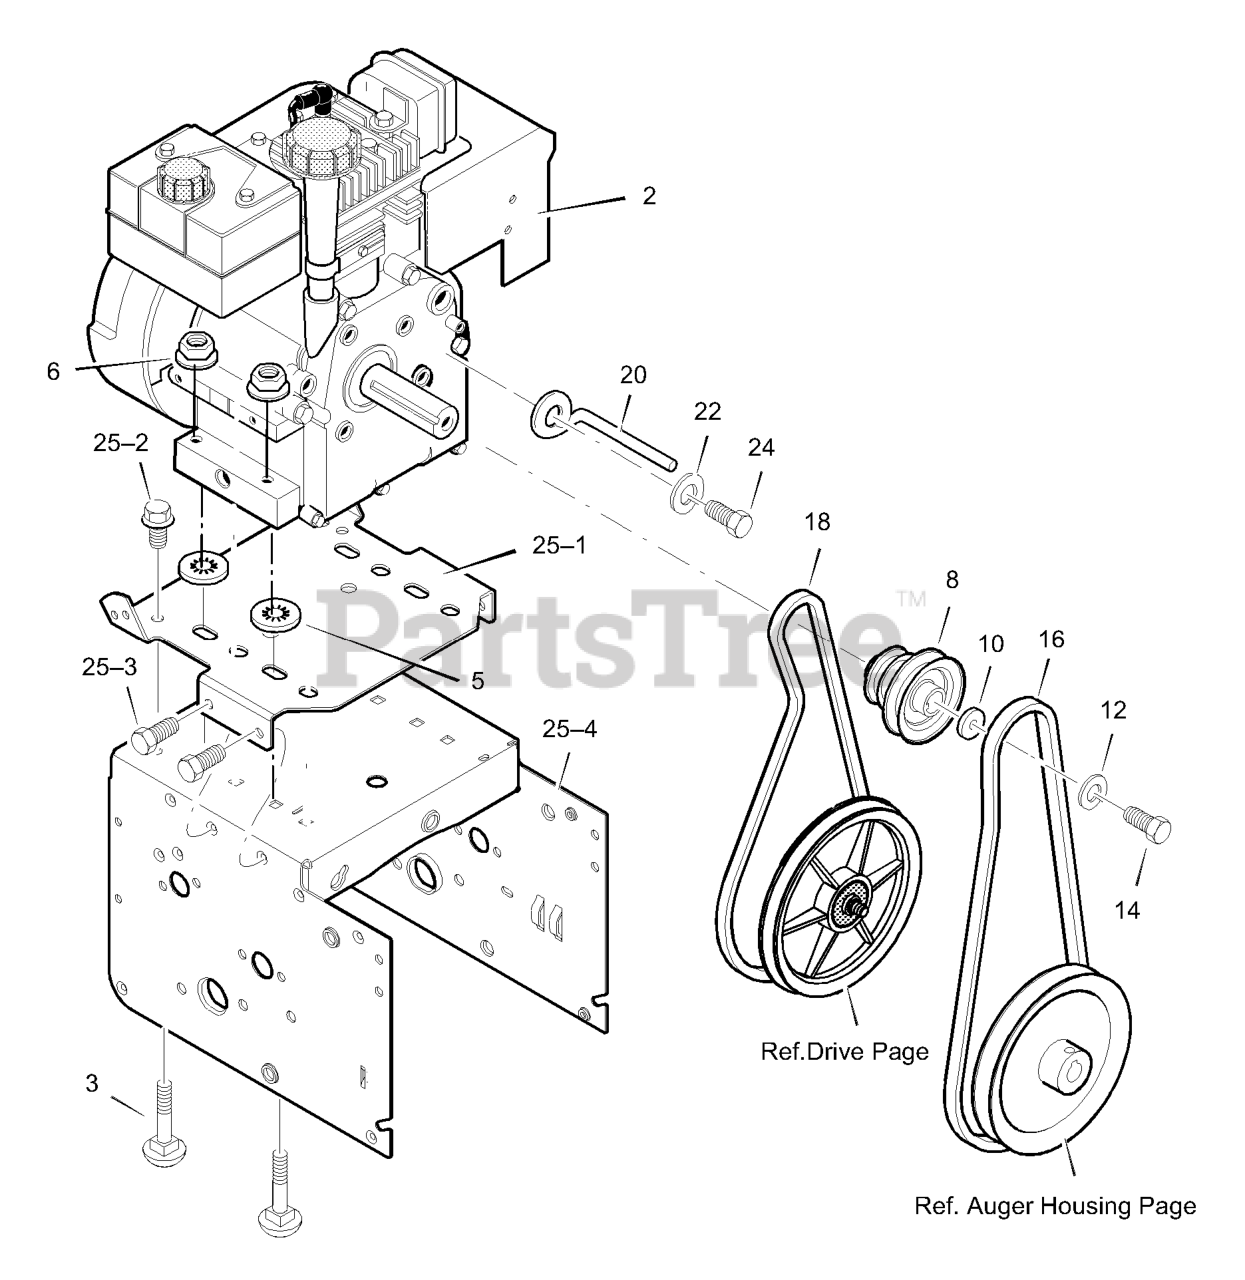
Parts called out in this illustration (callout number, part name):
2	ENGINE
3	BOLT, CARRIAGE 5/16-18
5	RETAINER, PUSH
6	NUT, HEXWDFLLK 5/16-18
8	PULLEY, ENGINE
10	WASHER
12	WASHER,HVSPTLK .38ID
14	SCREW, 3/8-24 x 1.00
16	BELT, V 4L 38.1MF16" 5-10
18	BELT, V 3L 33.13LG
20	GUIDE, BELT
22	WASHER, SPTLK .31X.58X.08
24	SCREW, 5/16-24 x 0.75
25	FRAME ASSEMBLY
25-1	PLATE, ENGINE MOUNT
25-2	SCREW, TAP 1/4-20 X .63
25-3	SCREW, TAP 5/16-18 X .50
25-4	FRAME, MOTOR BOX
